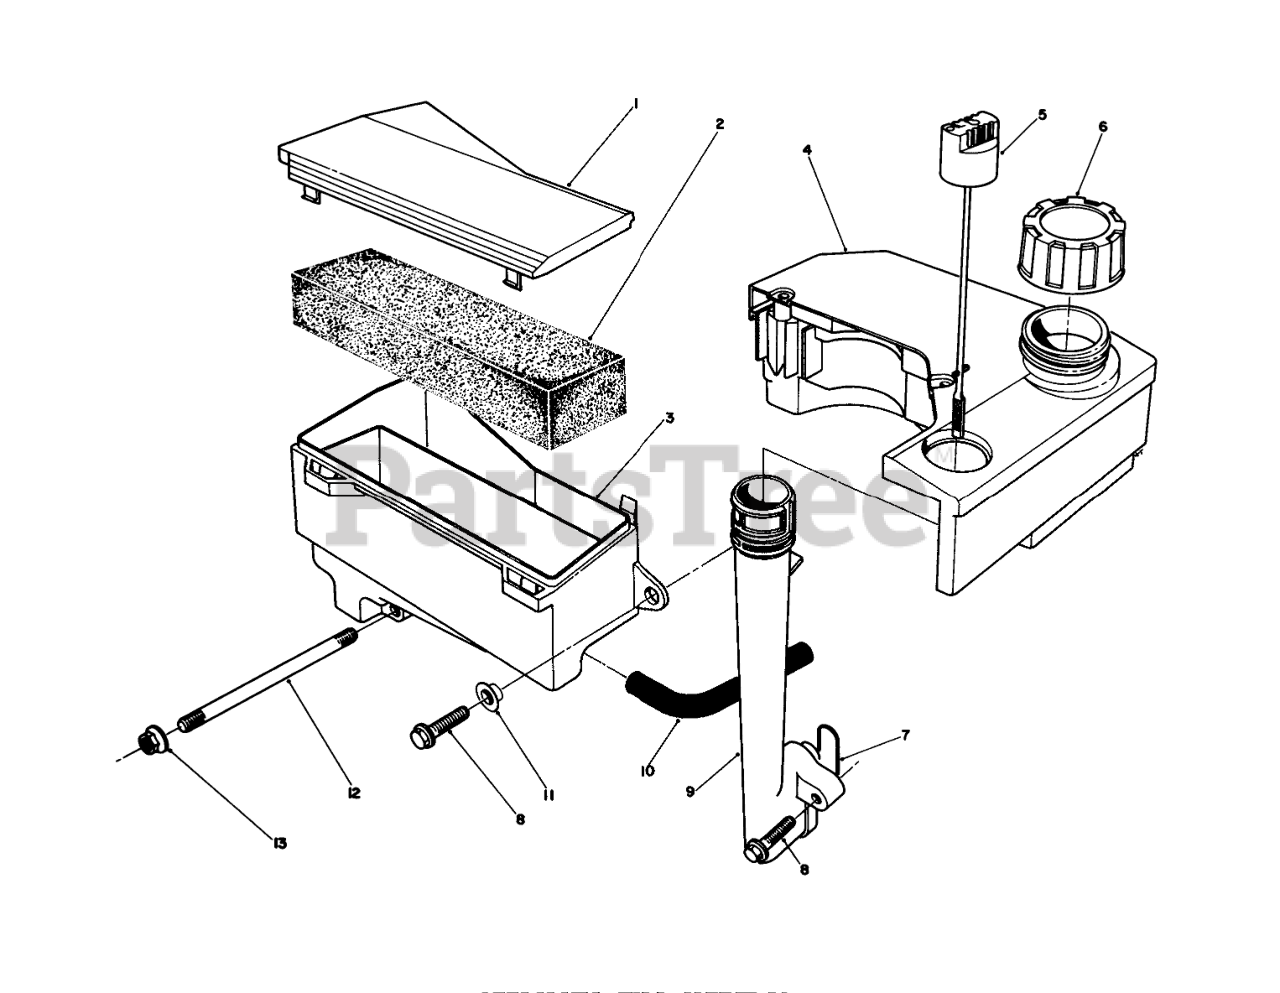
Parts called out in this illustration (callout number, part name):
1	AIR CLEANER CAP
3	Air Cleaner Assembly (Incl.Ref. #1)
4	TANK ASM
5	Dipstick
6	GAS CAP ASM
7	O-RING
11	SPACER
12	Stud-Carburetor
